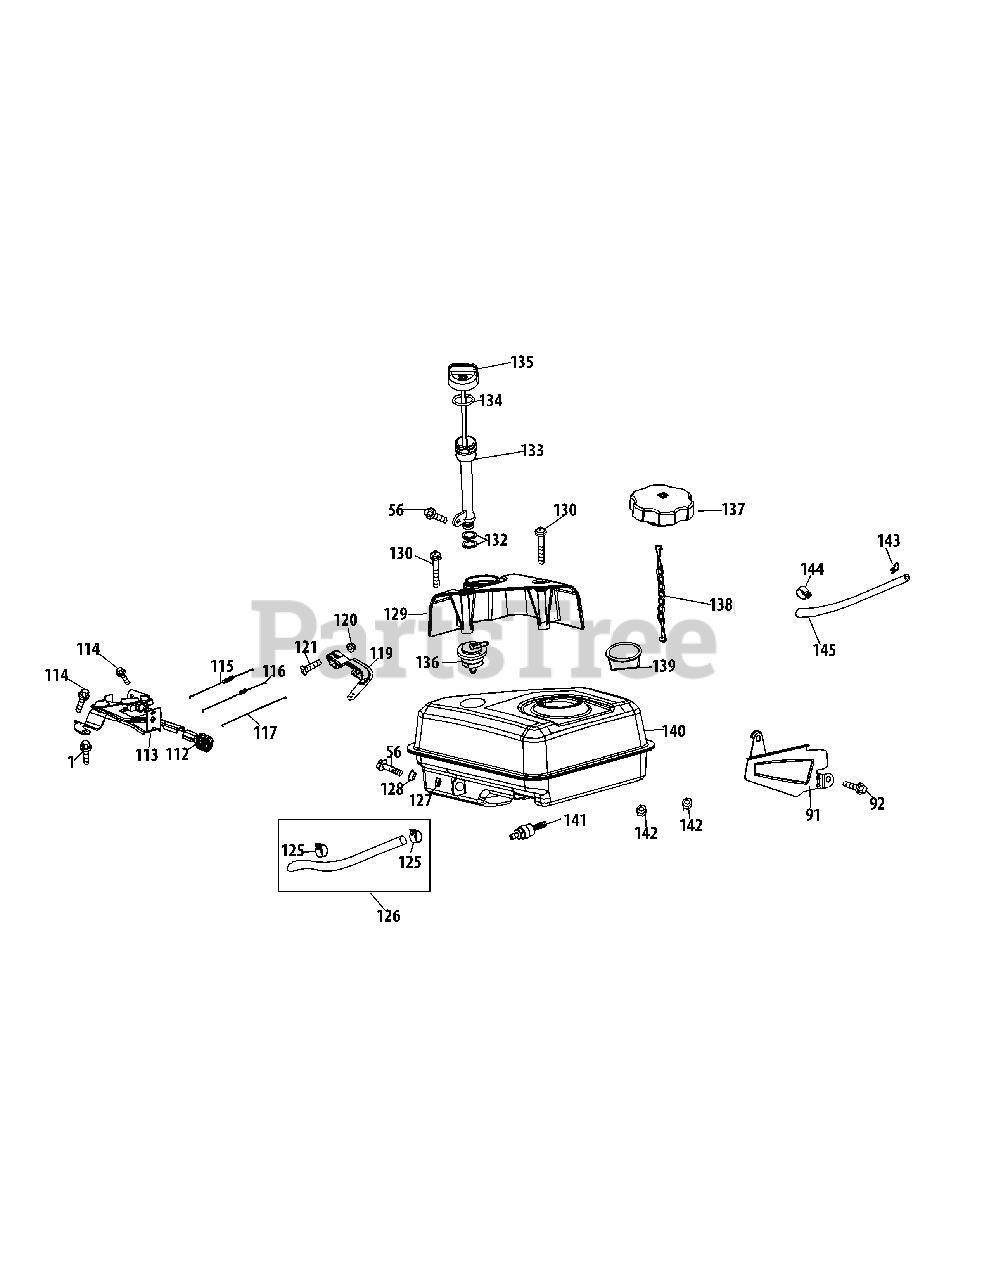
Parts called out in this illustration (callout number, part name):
1	Bolt M6×16
56	Bolt M6×12
91	Air Flow Shield
92	Bolt M6×10
112	Throttle Control Knob
113	Primer Bracket
114	Bolt M6×12
115	Governor Spring
116	Throttle Linkage Spring
117	Throttle Linkage
119	Governor Arm
120	Nut M6
121	Governor Arm Bolt
125	Fuel Hose Clamp
126	Kit-Fuel Line
127	Rubber Shock Pad
129	Dipstick Decoration Cover
132	Oil Fill Tube O-Ring
133	Oil Fill Tube Assey (Incl.132,133)
134	Oil Fill Tube O-Ring
135	Dipstick Assy - (Incl.134,135)
136	Roll Over Valve
137	Cap Comp,Fuel Feller
138	Fuel Cap Chain
139	Fuel Filter
141	Fuel Tank Nipple
143	Exhaust Piping
144	Hose Clamp
145	Primer Hose Assembly
